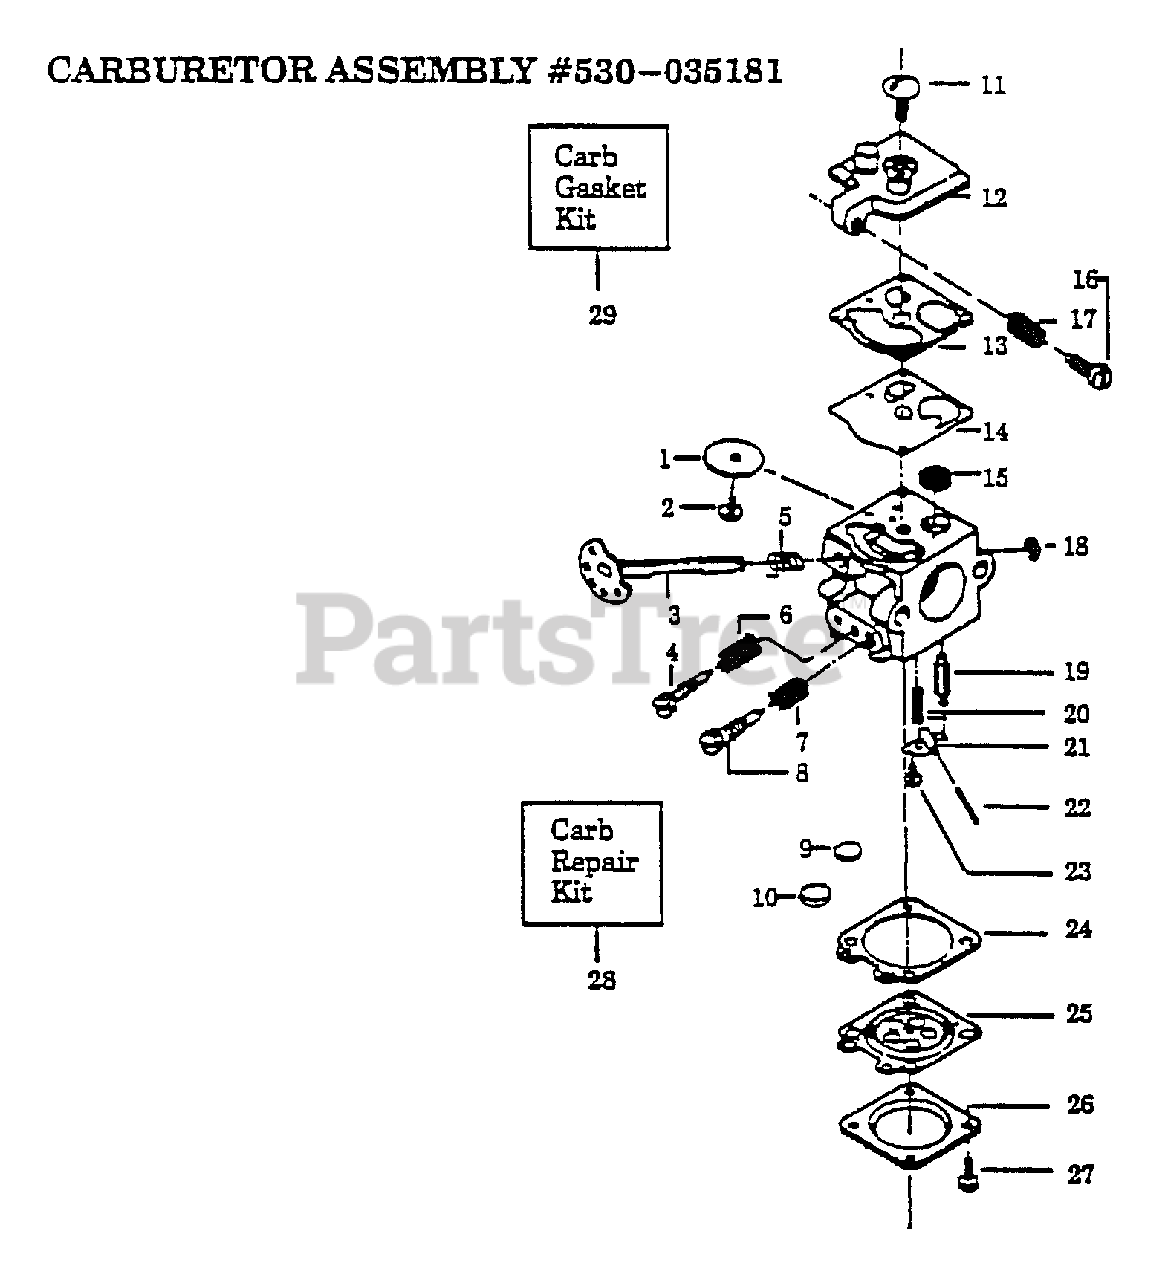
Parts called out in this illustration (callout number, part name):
1	Throttle Valve
2	Throttle Valve Screw
3	Throttle Shaft Ass'y.
4	Low Speed Mixture Needle
5	Throttle Return Spring
6	Low Speed Mixture Needle Spring
7	High Speed Mixture Needle Spring
8	High Speed Mixture Needle
9	Plug-5/16 Dia. Welch
10	Plug-1/4 Dia. Welch
11	Pump Cover Screw
12	Fuel Pump Cover
13	Fuel Pump Gasket
14	Fuel Pump Diaphragm
15	Fuel Inlet Screen
16	Idle Speed Adjusting Screw
17	Idle Speed Adjusting Screw Spring
18	Throttle Retainer Ring
19	Inlet Needle Valve
20	Metering Lever Spring
21	Metering Lever
22	Metering Lever Pin
23	Metering Lever Pin Screw
24	Metering Diaphragm Gasket
25	Metering Diaphragm
26	Metering Diaphragm Cover
27	Metering Cover Screw Ass'y
28	Carb. Repair Kit
29	Carb. Gasket/Diaphragm
